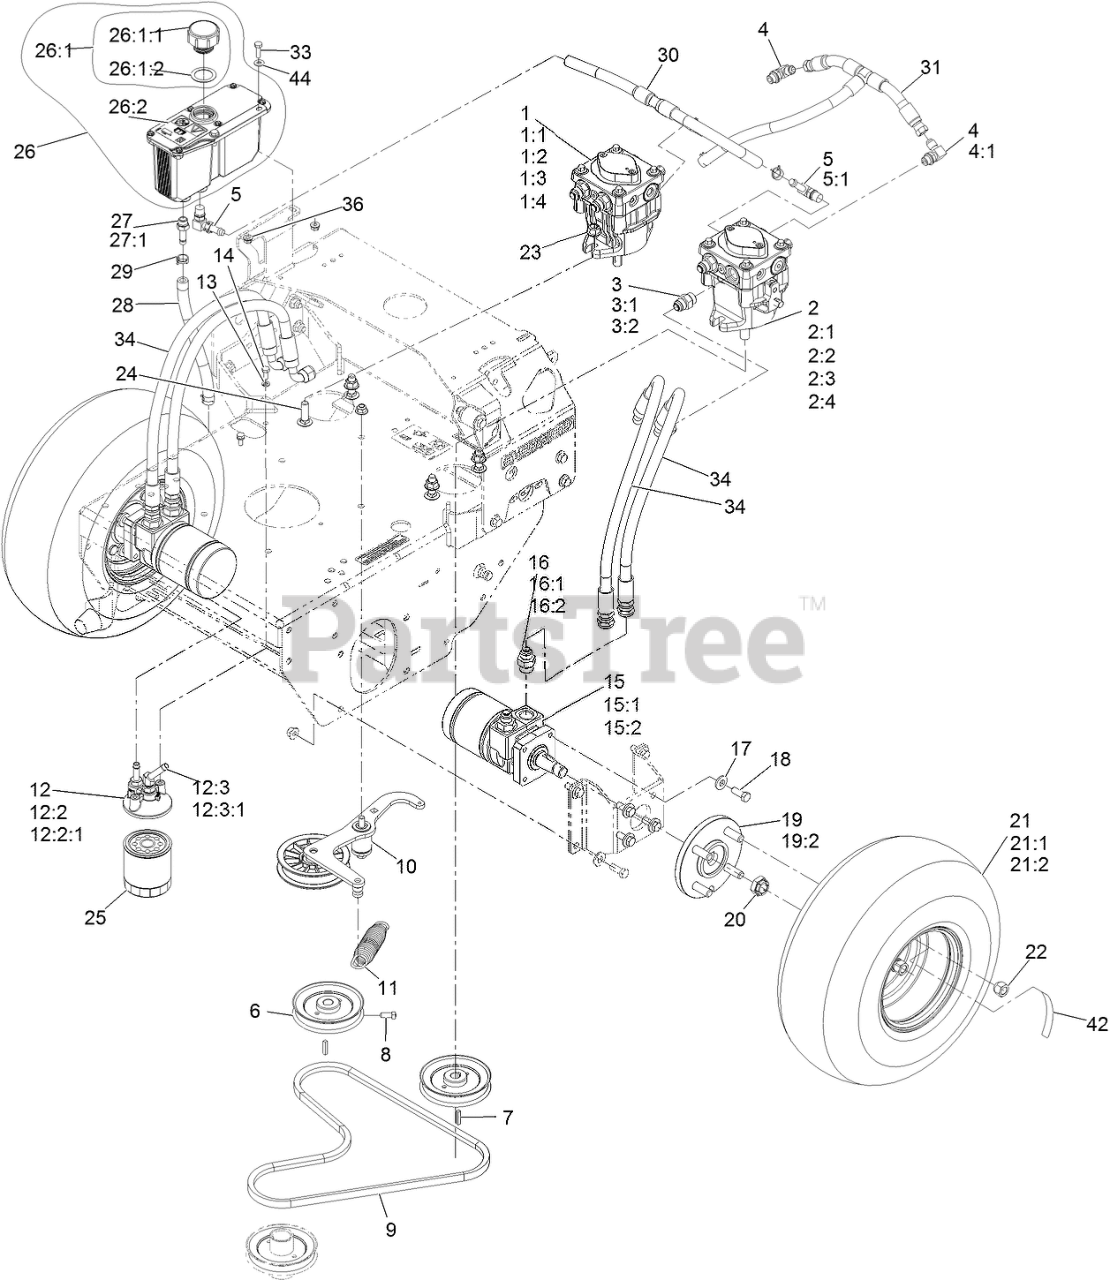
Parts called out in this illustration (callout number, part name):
1	RH HYD PUMP ASM
1:1	INPUT SHAFT KIT
1:2	BEARING-THRUST
1:3	CYLINDER BLOCK KIT
1:4	SEAL OVERHAUL KIT
2	LH HYD PUMP ASM
2:1	INPUT SHAFT KIT
2:2	BEARING-THRUST
2:3	CYLINDER BLOCK KIT
2:4	SEAL OVERHAUL KIT
3	FITTING-STRAIGHT
4	FITTING-ELBOW, 90 DEG
4:1	O-RING
5	FITTING-ELBOW, 90
5:1	O-RING
6	SHEAVE ASM
8	SCREW-SET, SQH
9	BELT
10	ASM, PUMP IDLER
11	SPRING-EXTENSION
12	ASM, FILTER HEAD
12:2	ADAPTER-STRAIGHT
12:2:1	O-RING
12:3	FITTING-BARBED, 45 DEG
12:3:1	O-RING
13	WASHER-LOCK
14	SCREW-HH
15	HYD MOTOR ASM
15:1	SEAL KIT
15:2	BEARING AND SEAL KIT
16	FITTING-STRAIGHT
16:1	O-RING
17	WASHER-BELLEVILLE
18	SCREW-HH
19	WHEEL HUB ASM
19:2	STUD-WHEEL
20	NUT-LOCK
21	WHEEL AND TIRE ASM
21:1	TIRE-TURFMASTER
21:2	RIM-WHEEL
22	NUT-LUG
23	NUT-HF, NI
24	BOLT-CARR
25	FILTER-25 MICRON, BI-DIRECTIONAL
26:1	Reservoir-HYD
26:1:1	Cap-Reservoir, HYD
26:1:2	GASKET-CAP
26:2	DECAL-WARNING
27	ADAPTER-STRAIGHT
27:1	O-RING
28	HOSE-CHARGE
29	CLAMP-HOSE
30	HOSE-CASE DRAIN
31	HOSE-CHARGE
33	SCREW-HH
34	HYD HOSE ASM
36	NUT-HHF
42	DECAL-TORQUE WHEEL LUG-HU
44	WASHER-FLAT
